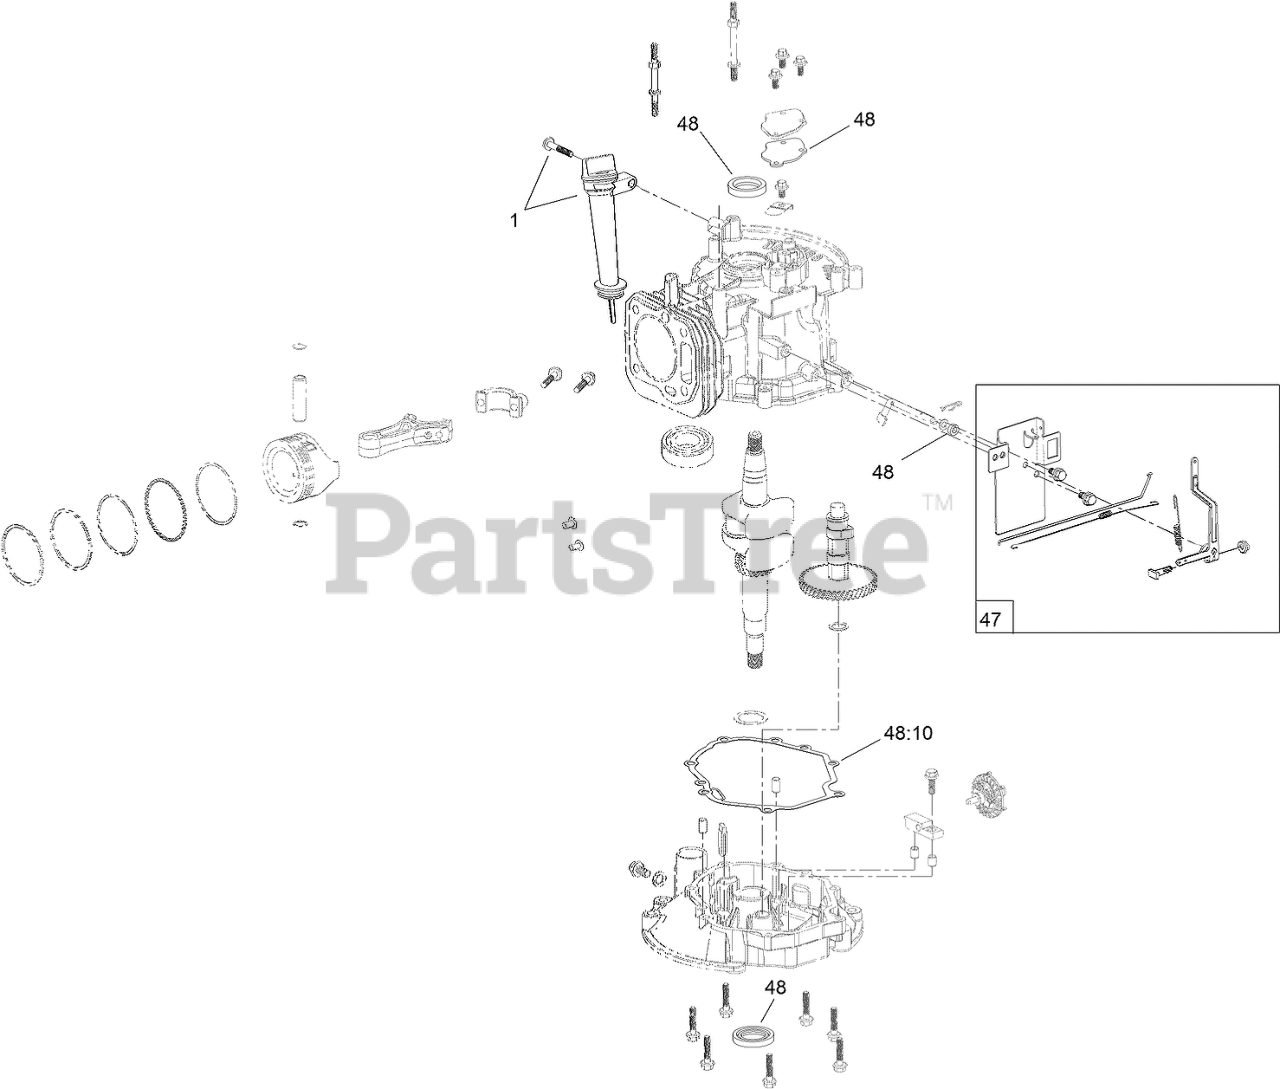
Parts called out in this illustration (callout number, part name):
1	DIPSTICK AND FILL TUBE KIT
47	GOVERNOR ARM KIT
48	SEAL AND GASKET KIT
48:10	GASKET-VALVE COVER
